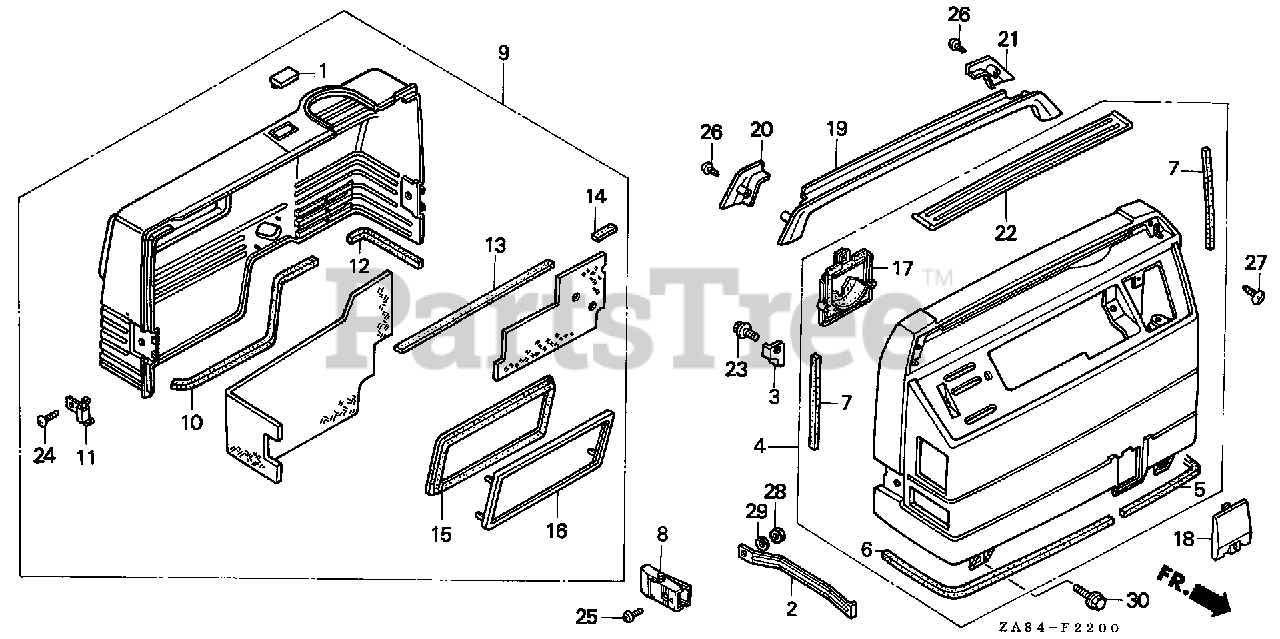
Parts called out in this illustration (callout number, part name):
1	CAP, FUEL METER
2	STAY, RECEPTACLE PANEL
3	HOLDER, RECEPTACLE PANEL
4	COVER ASSY., FR. *R8* (BRIGHT RED)
4	COVER ASSY., FR.
5	SEAL A, FR. COVER
6	SEAL B, FR. COVER
7	SEAL C, FR. COVER
9	COVER ASSY., RR.
10	SEAL, R. RR. COVER
11	SPRING, RR. COVER
12	SEAL, L. RR. COVER
13	SEAL, L. RR. COVER (UPPER)
14	SEAL, R. RR. COVER (UPPER)
15	RUBBER, RR. COVER SEAL
16	HOLDER, SEAL RUBBER
17	RUBBER, OIL CHECK
18	COVER, OIL CHECK
19	COVER, HANDLE
20	COVER, R. HANDLE
21	COVER, L. HANDLE
22	COVER, HANDLE (UPPER)
23	BOLT, FLANGE (5X10)
24	SCREW, PAN (5X6)
25	SCREW, PAN (5X16)
26	SCREW, TAPPING (4X25)
27	SCREW, TAPPING (4X10)
28	NUT, HEX. (5MM)
29	WASHER, SPRING (5MM)
30	BOLT, FLANGE (6X10)
